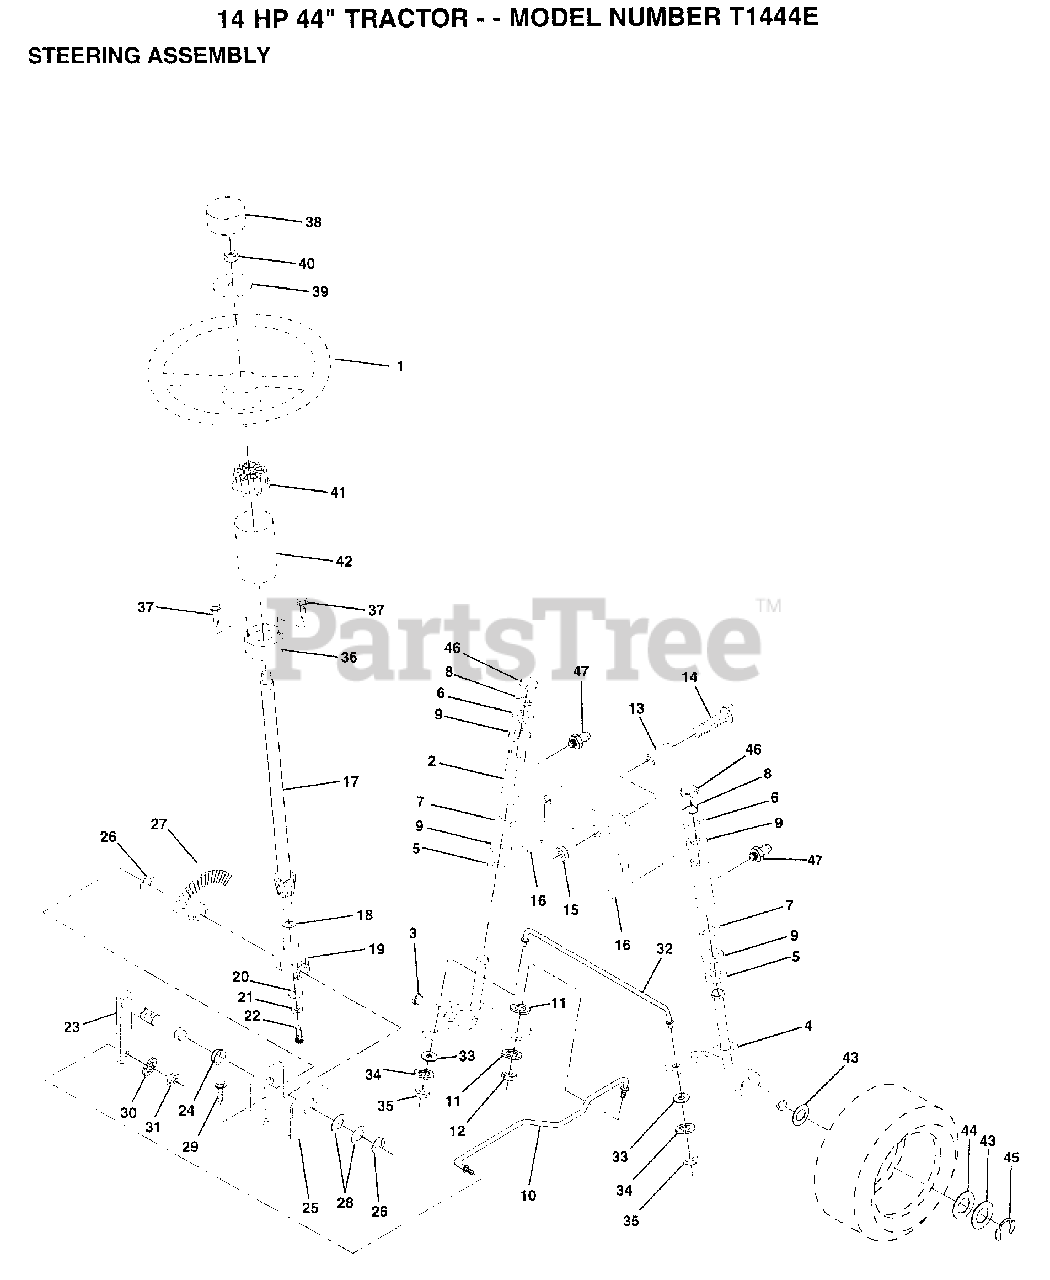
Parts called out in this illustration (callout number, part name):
2	AXLE ASM FRONT
3	SPINDLE LH
4	SPINDLE RH
5	WASHER .T
6	WASHER
7	WASHER
8	RING
9	COL. SRTG. BEAR.
11	LOCKWASHER
13	BEARING
14	BOLT HEX 5/8-11
15	"NUT-LOC,FLANGE LT"
16	AXLE PIN
17	SHAFT&GEAR STR T
18	THRUST WASHER
19	SUPPORT.SHAFT
21	LOCKWASHER
22	"SCREW,SPECIAL"
24	NYLINER T
25	"BRKT,STEERING"
26	RING
27	GEAR SECTOR
28	WASHER .T
29	SCREW
30	LOCKWASHER
32	TIE ROD
33	WASHER M
34	LOCKWASHER
35	NUT.LOCK.5/16-24
38	"INSERT,STR WHEEL"
39	WASHER
41	ADAPTER LT
43	WASHER
44	WASHER
45	RING
46	CAP
47	ZERK M
